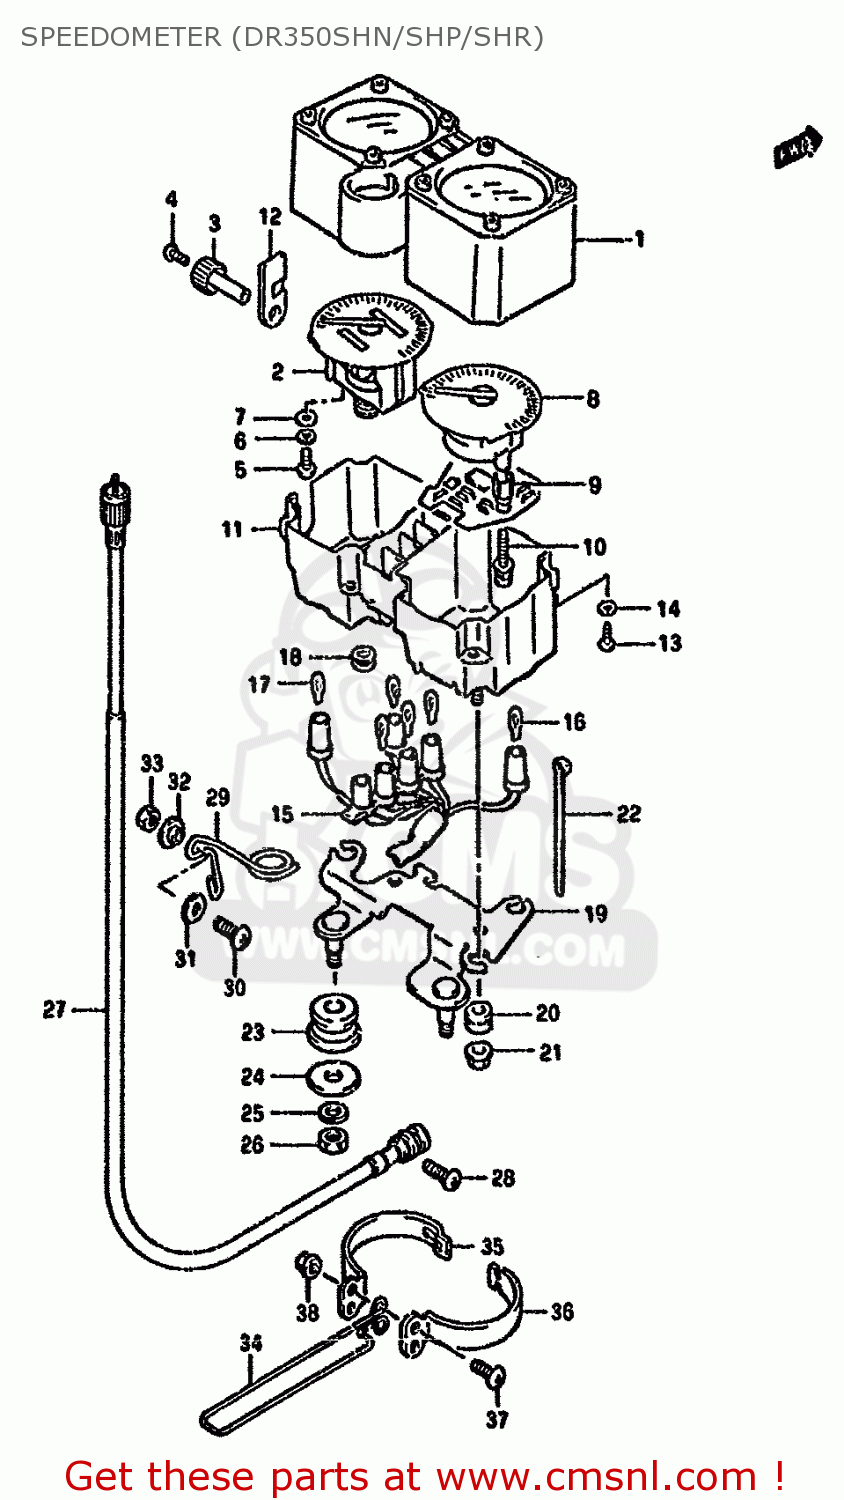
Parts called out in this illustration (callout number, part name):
1	HOOD,METER
2	SPEEDOMETER
3	KNOB,TRIP
4	SCREW,TRIP KNOB
5	SCREW
6	LOCK WASHER
7	WASHER 3.3X8X0
8	TACHOMETER
9	SPACER
10	SCREW
11	CASE,METER
12	CUSHION,METER
13	SCREW
14	LOCK WASHER
15	SOCKET,METER
16	BULB(12V3W,WB371,T7)
17	BULB(12V1.7W,WB372,T7)
18	CAP
19	BRACKET
20	CUSHION,METER
21	NUT
22	CLAMP
23	CUSHION,METER BRACKET
24	WASHER (8.5X20X1.6)
25	LOCK WASHER
26	NUT
27	CABLE ASSEMBLY,SPEEDOMETER
28	SCREW
29	GUIDE, CABLE NO.2
30	SCREW
31	WASHER
32	WASHER
33	NUT
34	GUIDE,CABLE
35	BRACKET,CABLE GUIDE
36	BRACKET,CABLE GUIDE
37	SCREW
38	NUT
